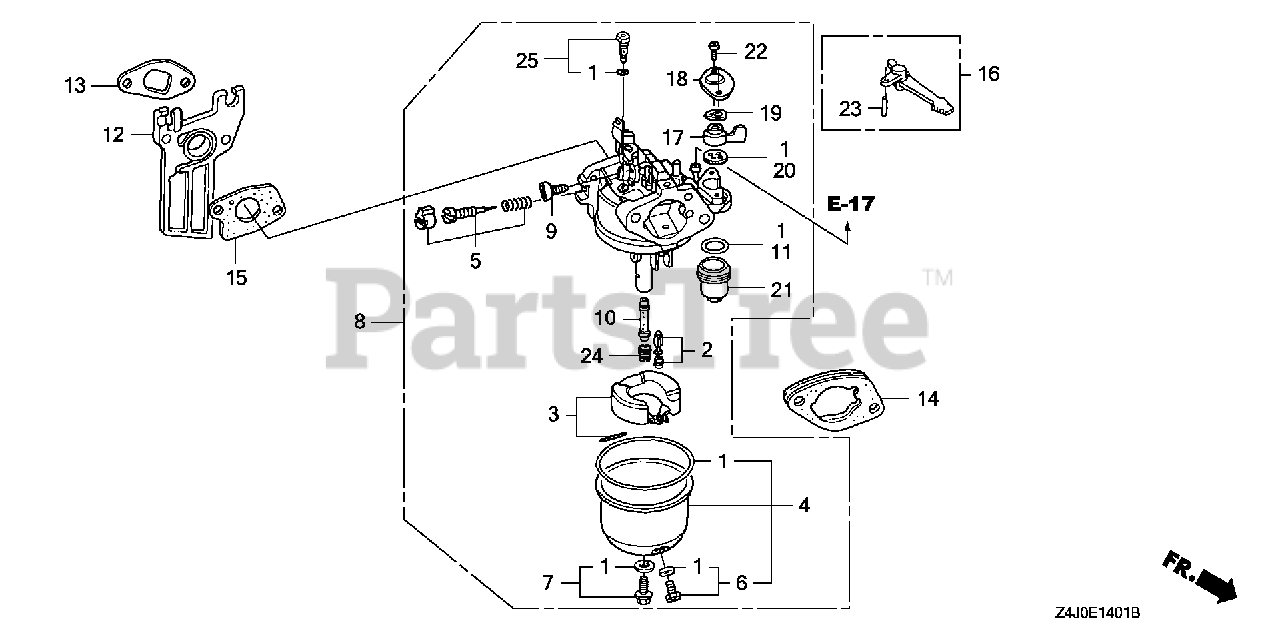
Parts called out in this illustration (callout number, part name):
1	GASKET SET
2	VALVE SET, FLOAT (SEAT NOT INCLUDED)
4	CHAMBER SET, FLOAT
5	SCREW SET, PILOT
6	SCREW SET, DRAIN
7	SCREW SET
8	CARBURETOR ASSY. (BE11C C)
9	SCREW, THROTTLE STOP
10	NOZZLE, MAIN
11	GASKET, FUEL STRAINER CUP
12	INSULATOR, CARBURETOR
13	GASKET, INSULATOR
14	SPACER, CARBURETOR
15	GASKET, CARBURETOR
16	LEVER, CHOKE (STD)
17	LEVER, PETCOCK
18	PLATE, LEVER SETTING
19	SPRING, PETCOCK LEVER
20	GASKET, PETCOCK
21	CUP, FUEL STRAINER
22	SCREW, PAN (3X6)
23	PIN, SPRING (2X12)
24	JET, MAIN (#62)
24	JET, MAIN (#65)
24	JET, MAIN (#68)
25	JET SET, PILOT (#38)
